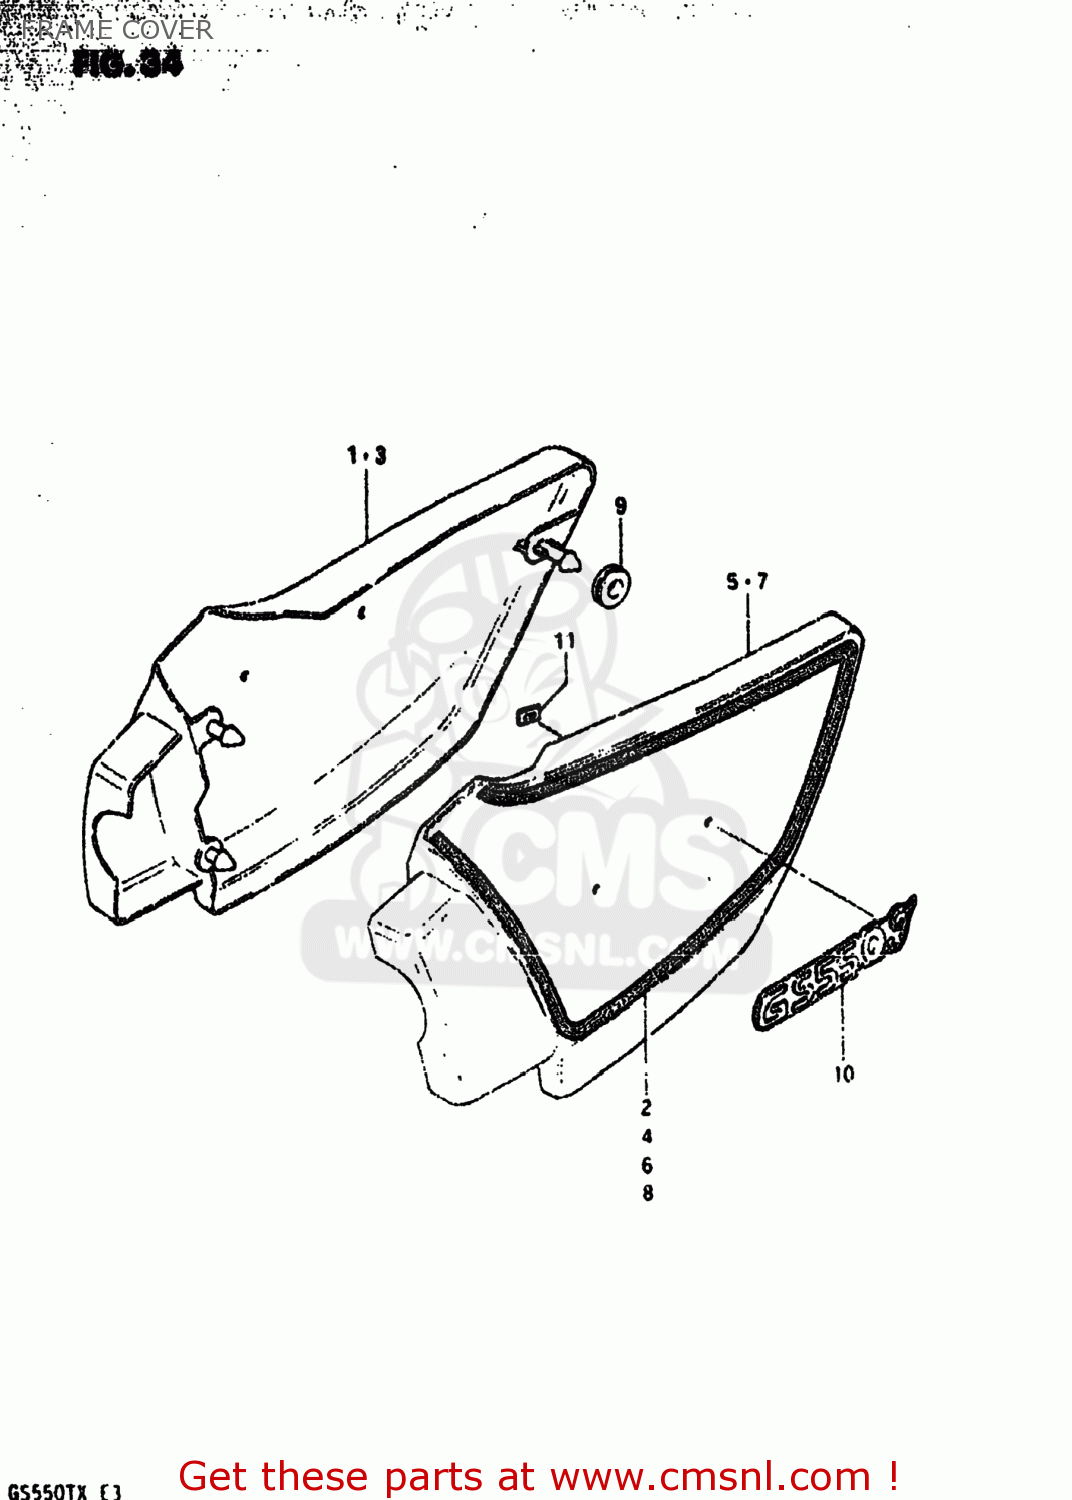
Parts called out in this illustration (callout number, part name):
1	COVER,FRAME,RIGHT
2	TAPE SET,FRAME COVER
3	COVER,FRAME,RIGHT
4	TAPE SET,FRAME COVER
5	COVER,FRAME,LEFT
6	TAPE SET,FRAME COVER
7	COVER,FRAME,LEFT
8	TAPE SET,FRAME COVER
9	CUSHION
10	EMBLEM,FRAME COVER (GS
11	NUT
